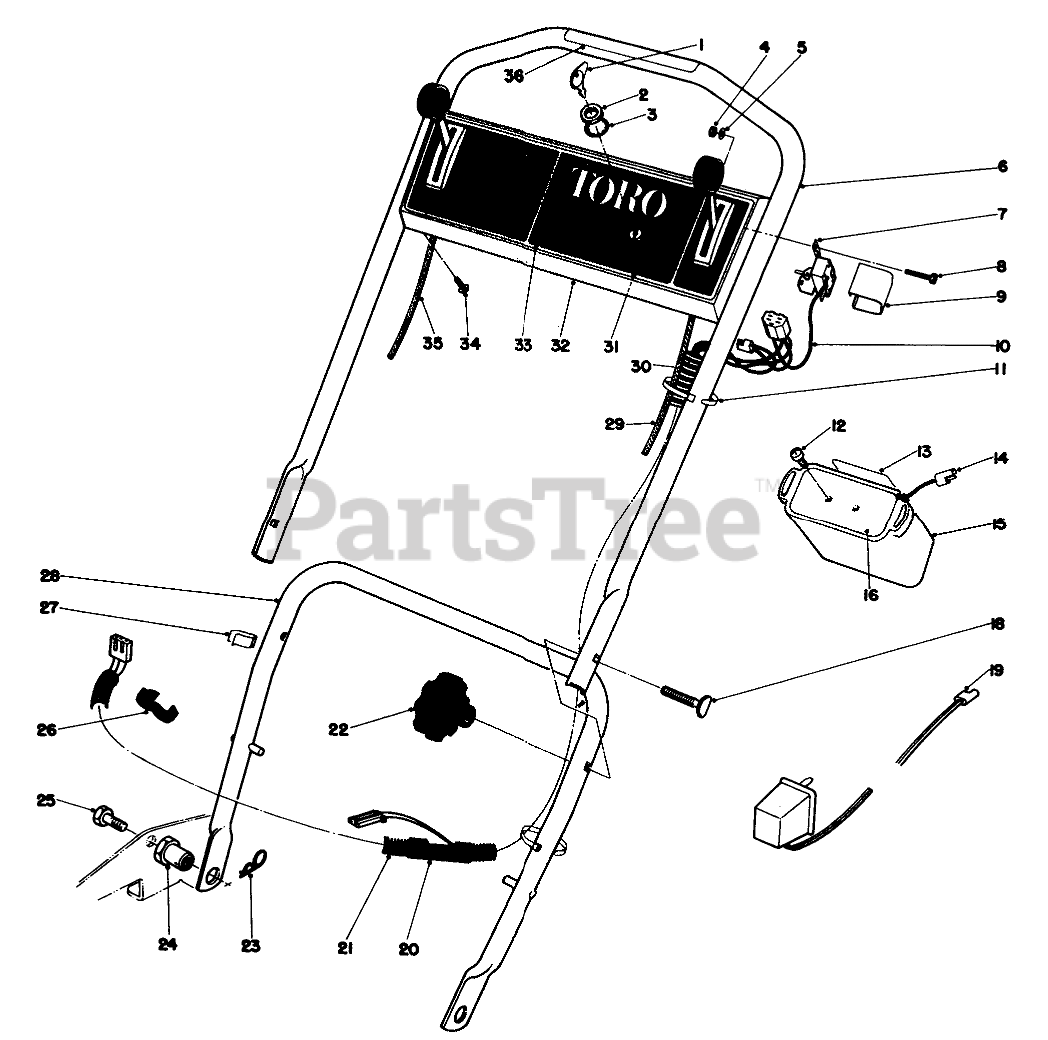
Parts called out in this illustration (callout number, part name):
1	Key
2	NUT-HH
3	WASHER-TOOTH, INTERNAL
4	NUT-HEX
5	WASHER-FLAT
6	UPPER HANDLE
7	Safety Switch
8	SCREW-HH
9	Cover Switch
10	Wiring Harness
11	216 Washer
12	10-190X1/2 PAN HD SCR
13	Decal
14	Plug & Wire
15	Battery Case
16	BATTERY COVER
18	SCREW-HANDLE
19	Charger
20	Breakout Fitting
21	Cover Wiring Harness Lower
23	PIN-COTTER, HAIR
24	HANDLE PIVOT NUT
25	SCREW-HH
26	RING FITTING
28	LOWER HANDLE ASM
29	Traction Control
30	Cover-Wiring Harness Upper
31	Switch Starter (Incl. Ref. #1-3)
32	Control Plate
33	Decal Control Plate
34	SCREW-HWHTF
35	Throttle Control
36	Decal-Instruction
